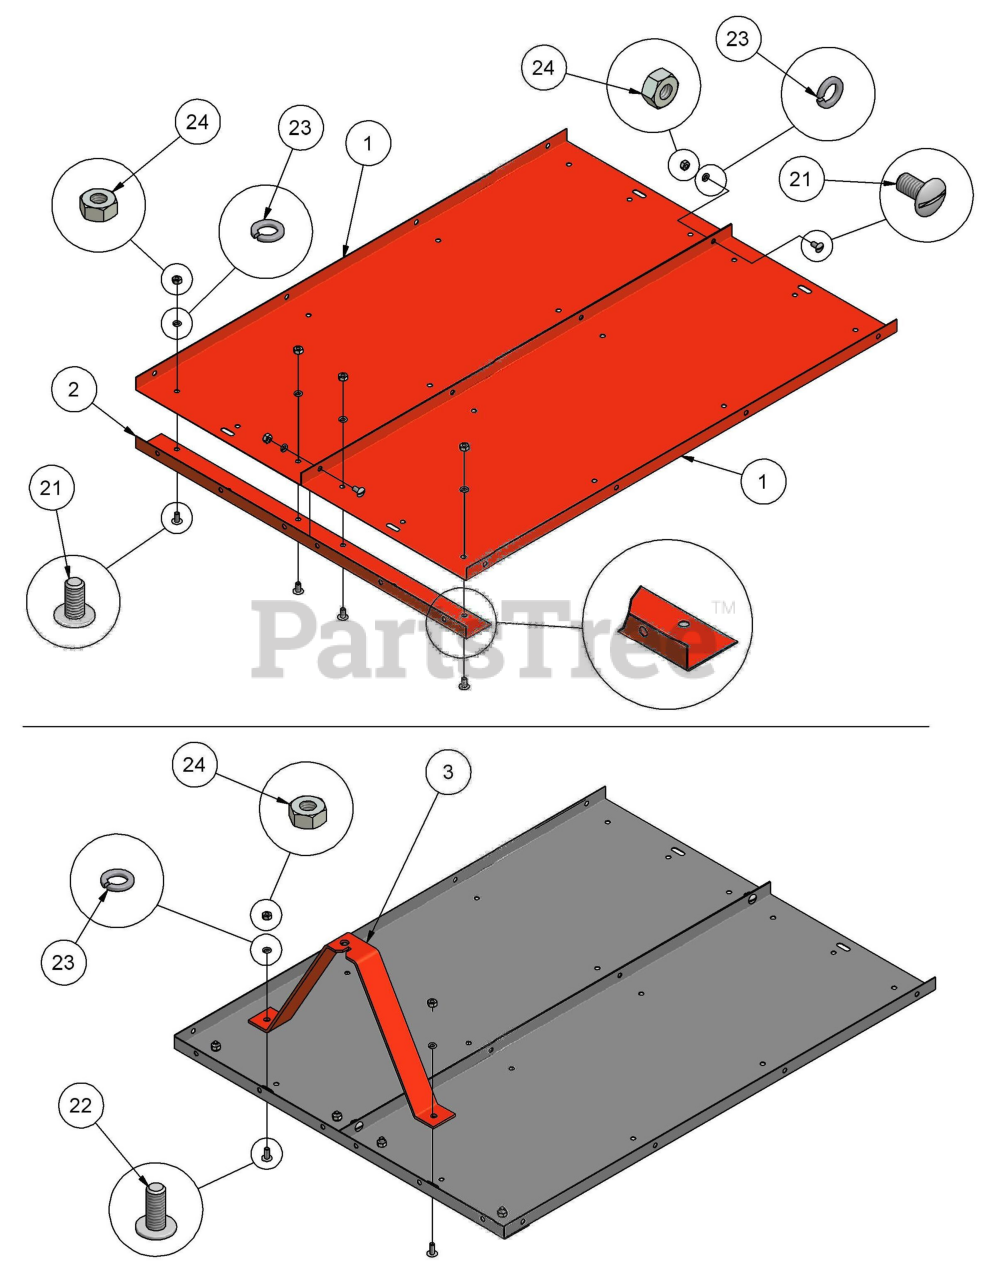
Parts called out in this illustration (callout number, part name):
1	BOTTOM PANEL
2	FRONT CROSS BRACE
3	TONGUE SUPPORT
21	M8 X 16 TRUSS HEAD BOLT
22	M8 X 20 TRUSS HEAD BOLT
23	8MM LOCK WASHER
24	8MM HEX NUT
